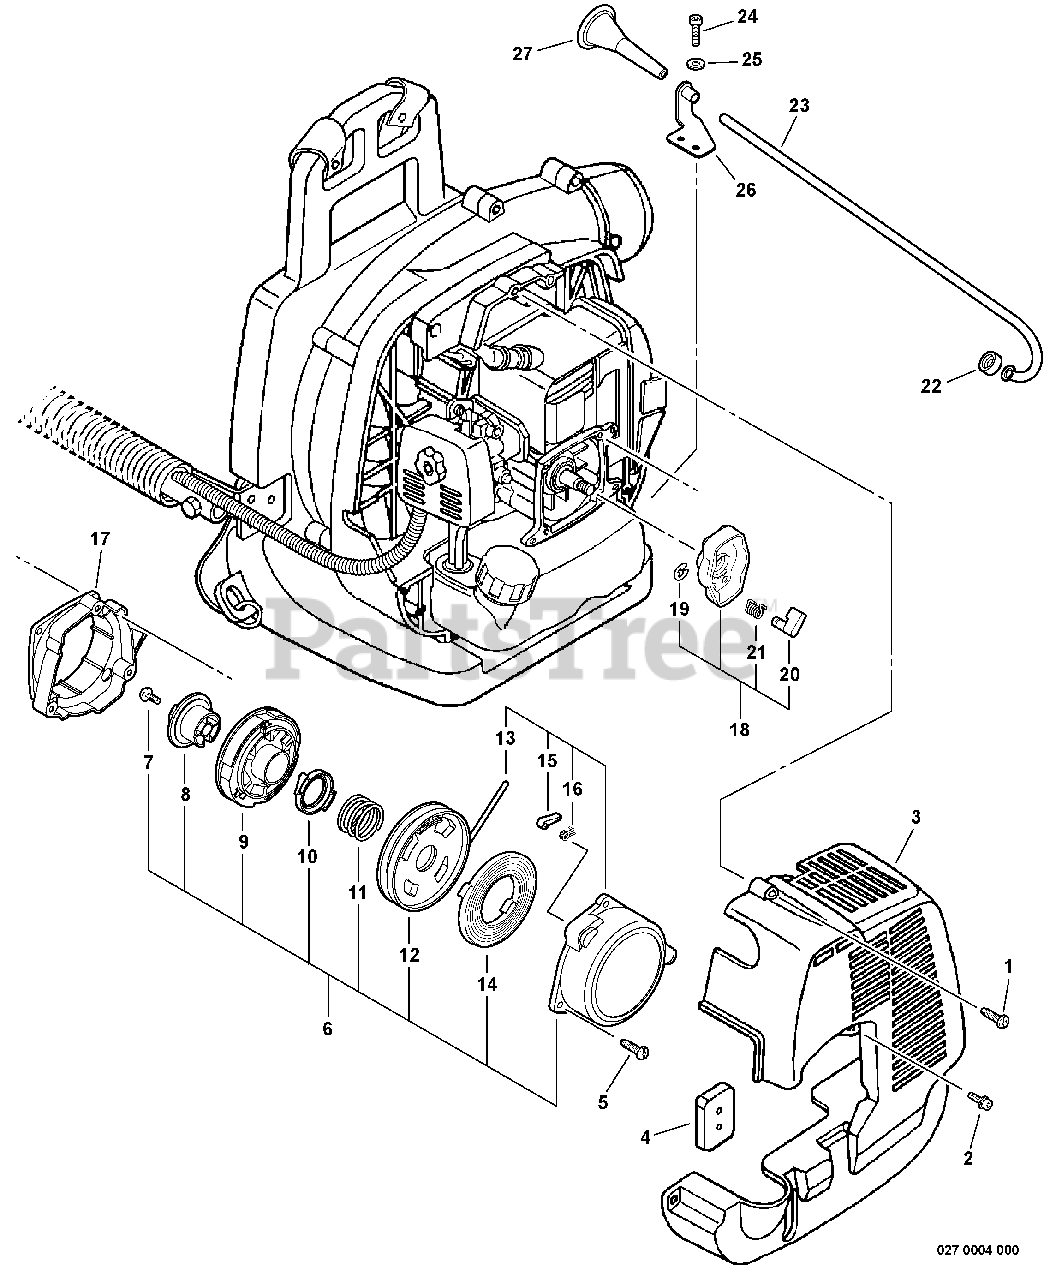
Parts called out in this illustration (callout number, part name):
1	SCREW - 5X20 -- TAPPING
2	SCREW - 4X16
3	COVER, ENGINE
4	CUSHION, FUEL TANK - FRONT
5	SCREW - 5X20 -- TAPPING
6	STARTER ASSY
8	PLATE, CAM
9	SPRING ASSY
11	SPRING, RETURN
12	REEL, ROPE
13	ROPE, STARTER - 3X1220
14	SPRING, REWIND
15	PAWL, STARTER
16	SPRING, PAWL RETURN
17	MOUNT, STARTER
18	STARTER PAWL ASSY
19	RING, RETAINING - 4
20	PAWL, STARTER
21	SPRING, RETURN
22	CUSHION
23	GUIDE, ROPE
24	SCREW - 5X12
25	WASHER - 5
26	BRACKET, ROPE GUIDE
27	GRIP, STARTER
